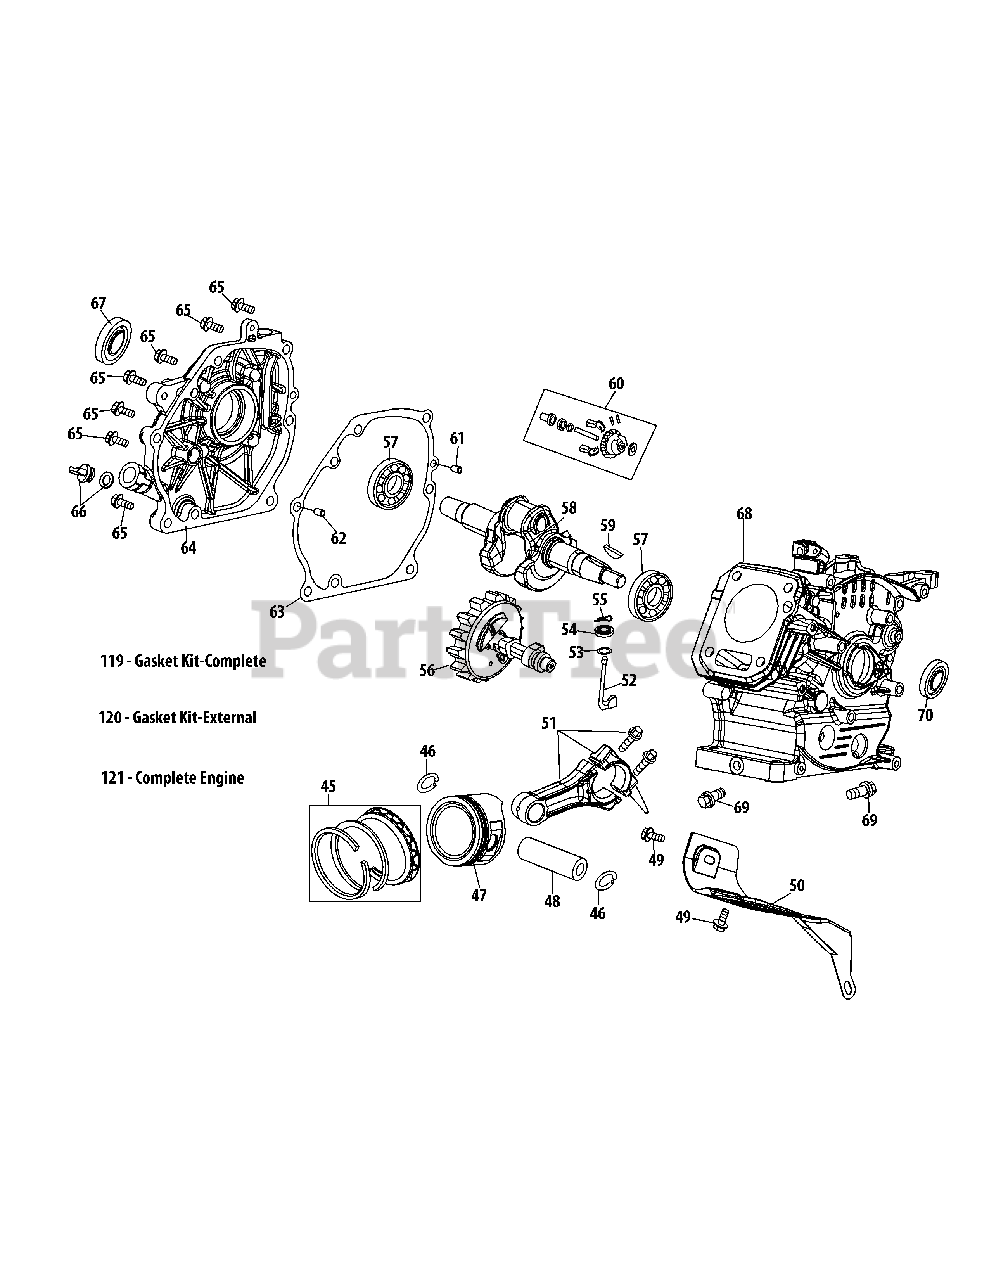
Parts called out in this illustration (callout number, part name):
45	Piston Ring Set
46	Piston Pin Snap Ring
47	Piston
48	Piston Pin
49	Bolt M6×12
50	Air Shield
51	Connecting Rod Assembly
52	Governor Arm
53	Washer - 5.2 X 1.9
54	Governor Seal
55	Cotter Pin
56	Camshaft Assembly
57	Radial Ball Bearing, 6205
58	Crankshaft Kit
59	Woodruff Key
60	Governor Gear/Shaft Assembly
61	Dowel Pin 7×14
62	Dowel Pin 9×14
63	Crankcase Cover Gasket
64	Crankcase Cover
64	Crankcase Cover Kit
65	Bolt M8×32
66	Oil Fill Plug Assembly
66	O-Ring
67	Oil Seal
68	Crankcase Service Kit
68	Short Block Assembly
69	Oil Drain Plug
70	Oil Seal
119	Gasket Kit-Complete
120	Gasket Kit-External
121	Complete Engine
